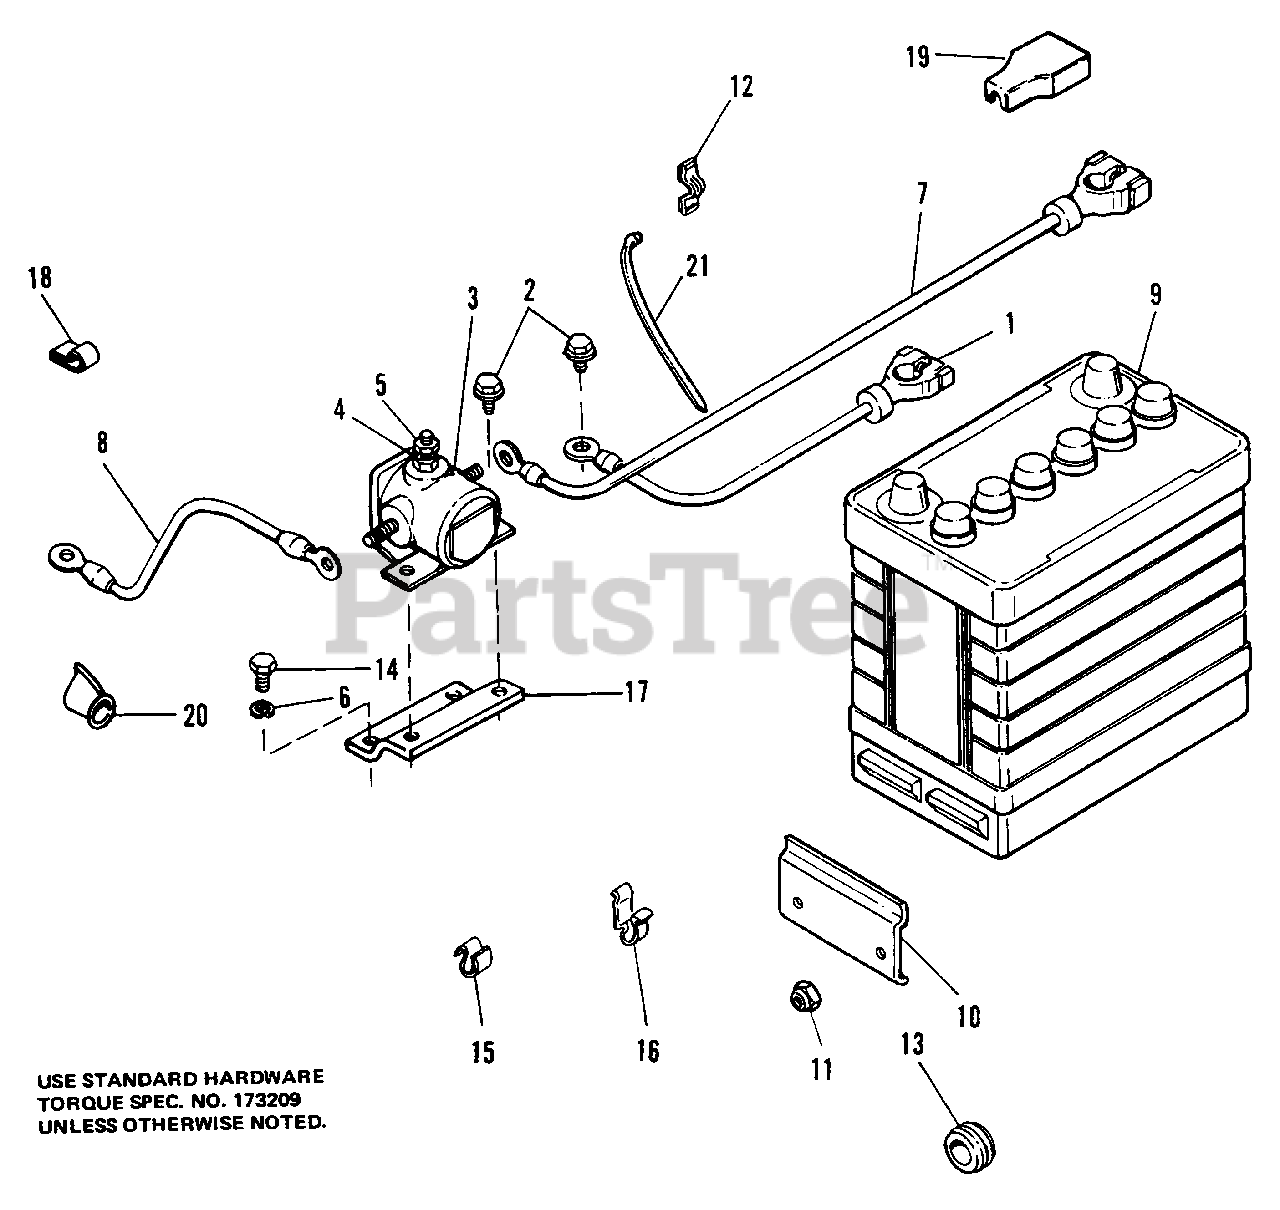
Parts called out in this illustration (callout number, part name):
1	CABLE, Battery to Ground
2	SCREW, Taptite, 1/4-20 x 1/2
4	LOCKWASHER, No. 10
5	NUT, Hex, No. 10-32
6	LOCKWASHER, 5/16
7	CABLE, Battery to Solenoid
8	CABLE. Solenoid to Starter
11	NUT, Elastic, 5/16-18
12	CLIP, Wire
14	CAPSCREW, Hex Hd., 5/16-18 x 3/4
15	CLIP, Tinnermann
16	CLIP, Tinnermann
18	CLIP, Cable
19	PROTECTOR, Terminal
20	COVER, Terminal
